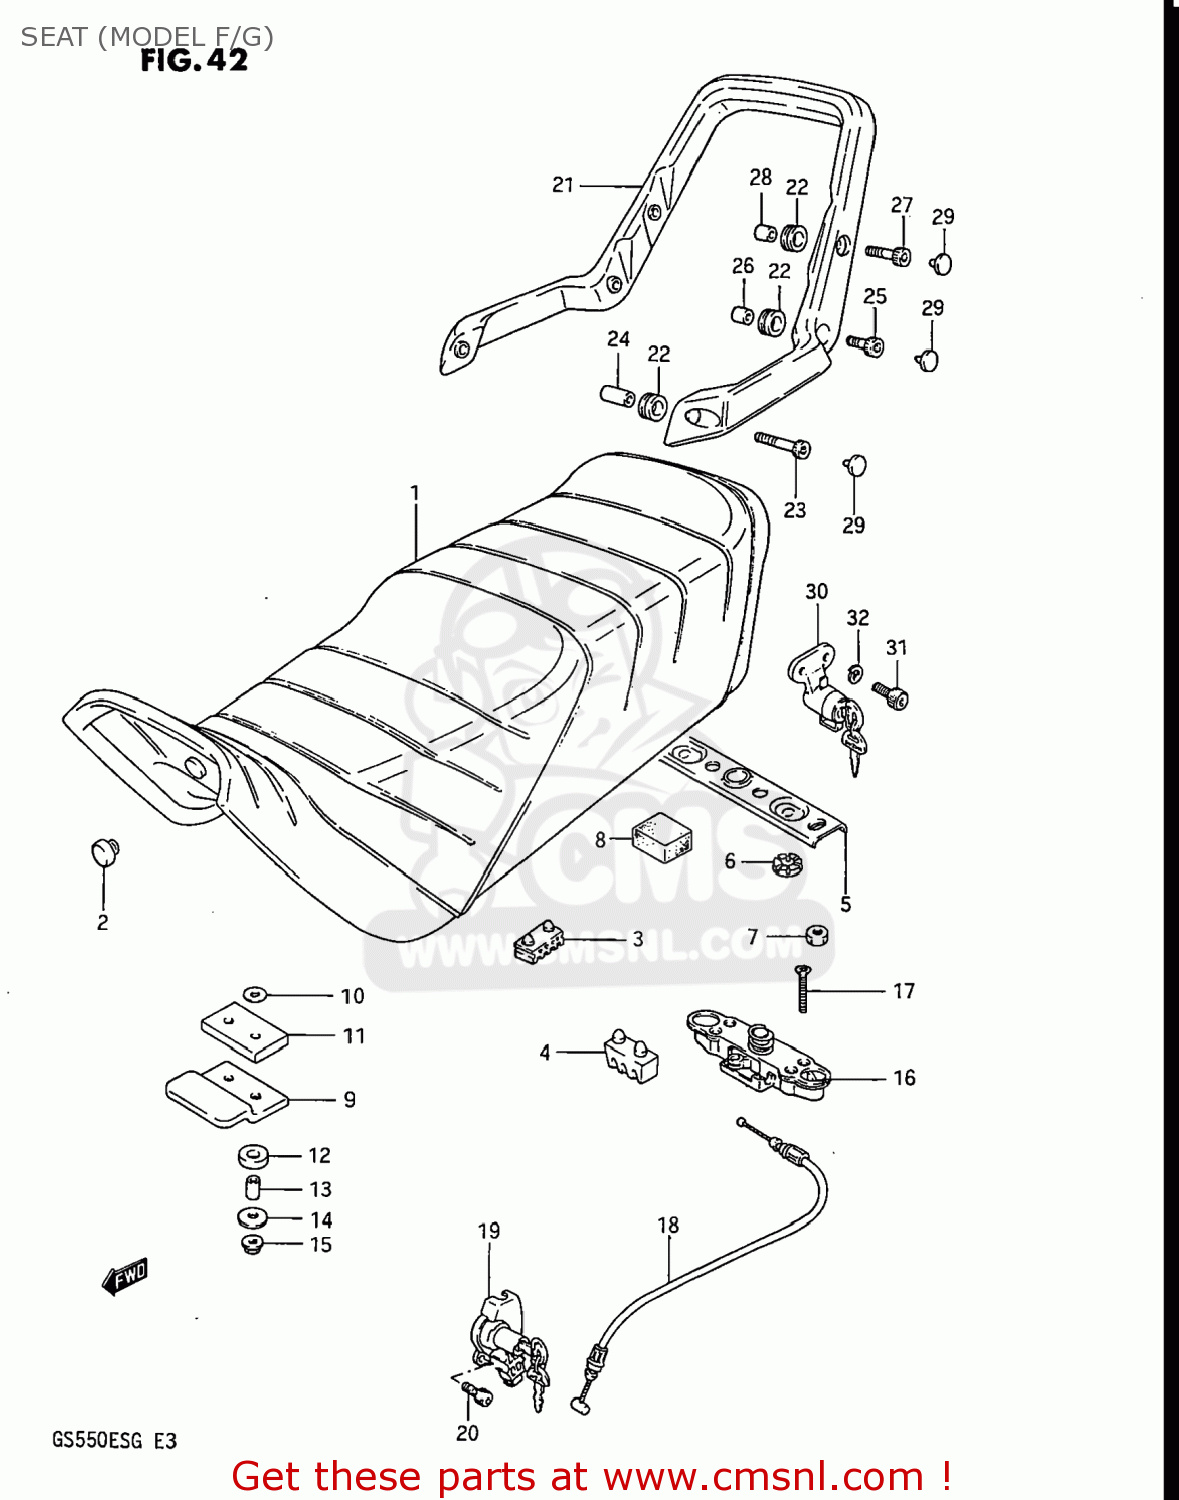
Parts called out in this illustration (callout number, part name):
1	SEAT ASSEMBLY
2	CUSHION
3	CUSHION,SEAT(40X20X15)
4	CUSHION,SUPPORT(50X25X32)
5	STRIKER, SEAT LOCK
6	CUSHION,STRIKER
7	NUT
8	CUSHION(30X60X10)
9	PLATE,SEAT HOOK,FRONT
10	WASHER
11	CUSHION,SEAT
12	CUSHION
13	SPACER (6.1X8X12)
14	WASHER
15	NUT
16	LOCK ASSY,SEAT STRIKER
17	SCREW,6X30
18	CABLE,SEAT LOCK
19	LOCK ASSEMBLY,SEAT & HELMET
20	BOLT
21	HANDLE,PILLION RIDER
22	GROMMET,PILION RIDER HANDLE
23	BOLT
24	SPACER,PILLION RIDER HOLDER
25	BOLT
26	SPACER,PILLION RIDER HOLDER
27	BOLT
28	SPACER,PILLION RIDER HOLDER
29	CAP(OD:10)
30	LOCK ASSEMBLY,HELMET
31	BOLT
32	WASHER,LOCK
